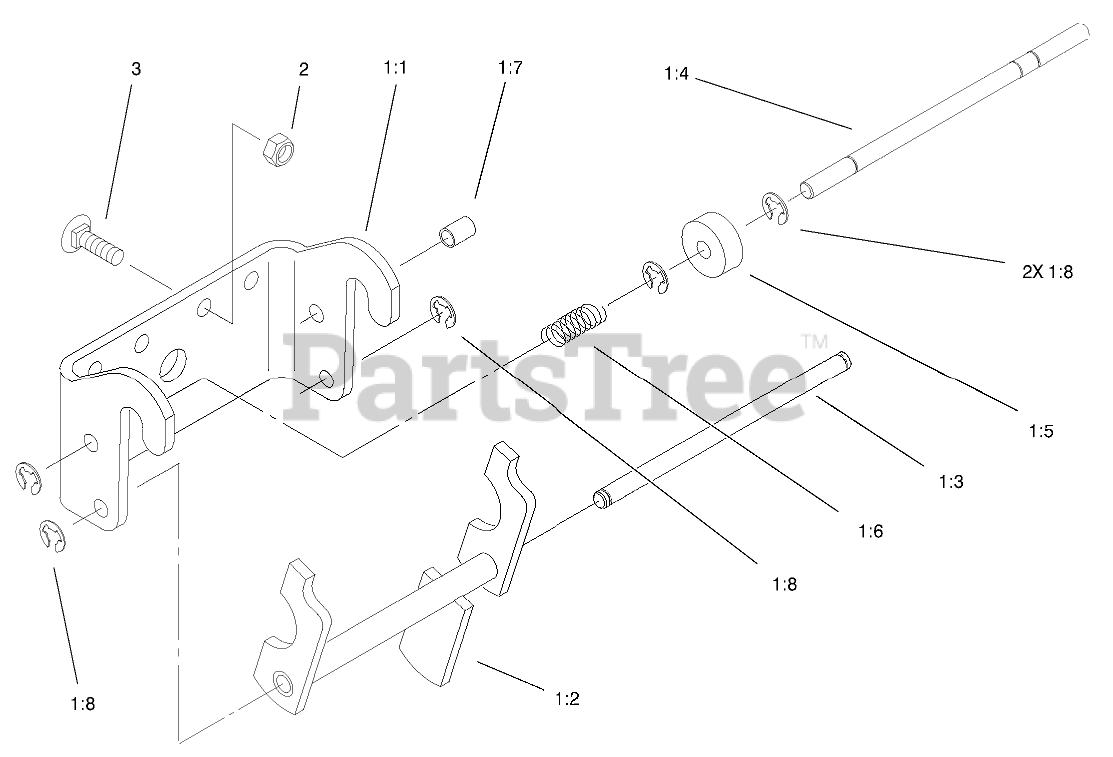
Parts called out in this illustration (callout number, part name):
1:1	HITCH-FRONT
1:2	LATCH
1:3	ROD-LATCH PIVOT
1:4	ROD-LOCK
1:6	SPRING
1:7	CAP-ROD, PLUNGER
1:8	RING-RETAINING
2	NUT-LOCK, NI
3	SCREW-CARR
